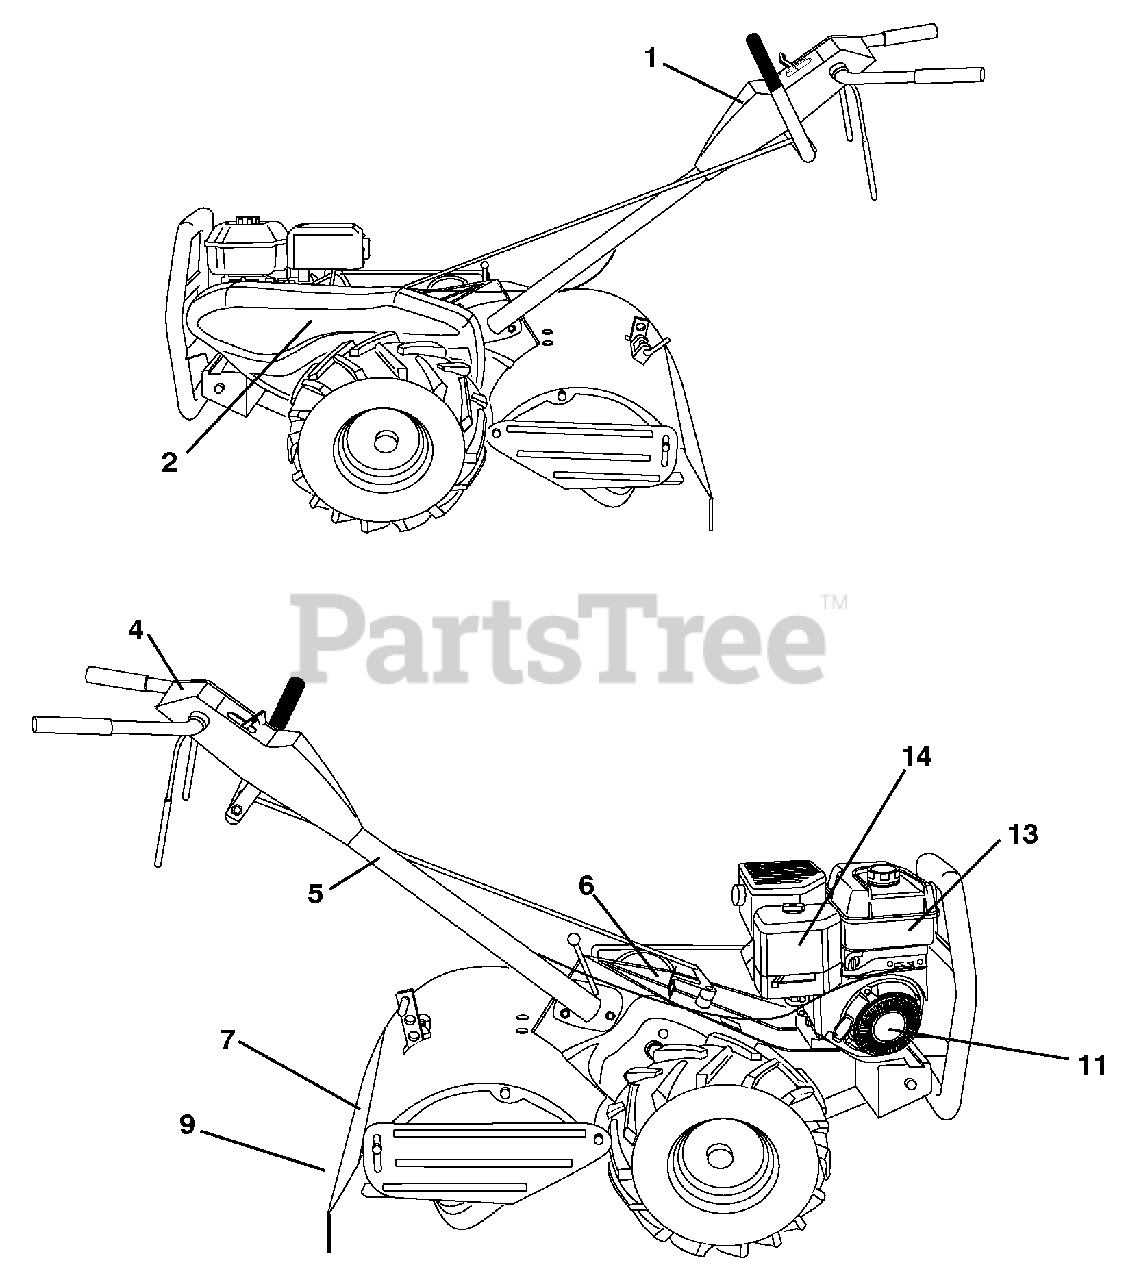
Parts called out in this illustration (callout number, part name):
1	Decal, CNTRL PNL
2	Decal, Decal, Blt Grd
4	Decal, Instruction, Tilling
5	Decal, Hand Placement
6	Decal, Shift Indicator
7	Decal, Caution
9	Decal, Warning, Rotating Tines
11	Decal, Rewind
13	Decal, B&S Tank
14	Decal, B&S, Air Cleaner
14	Manual, Operator's, English/French
14	Manual, Repair Parts, English/French
